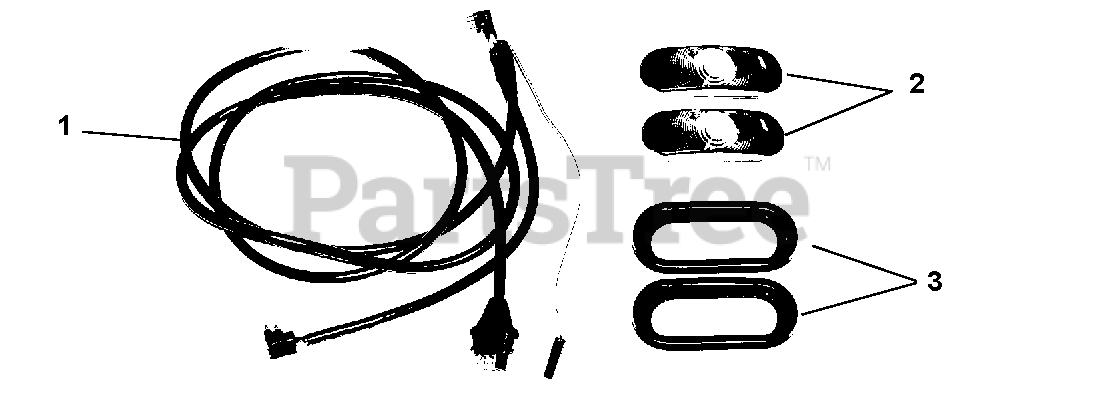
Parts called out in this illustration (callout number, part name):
1	Wiring Harness, Trailer Light Kit
2	Housing, Tail Light With Bulb
3	Grommet, Tail Light Mounting
